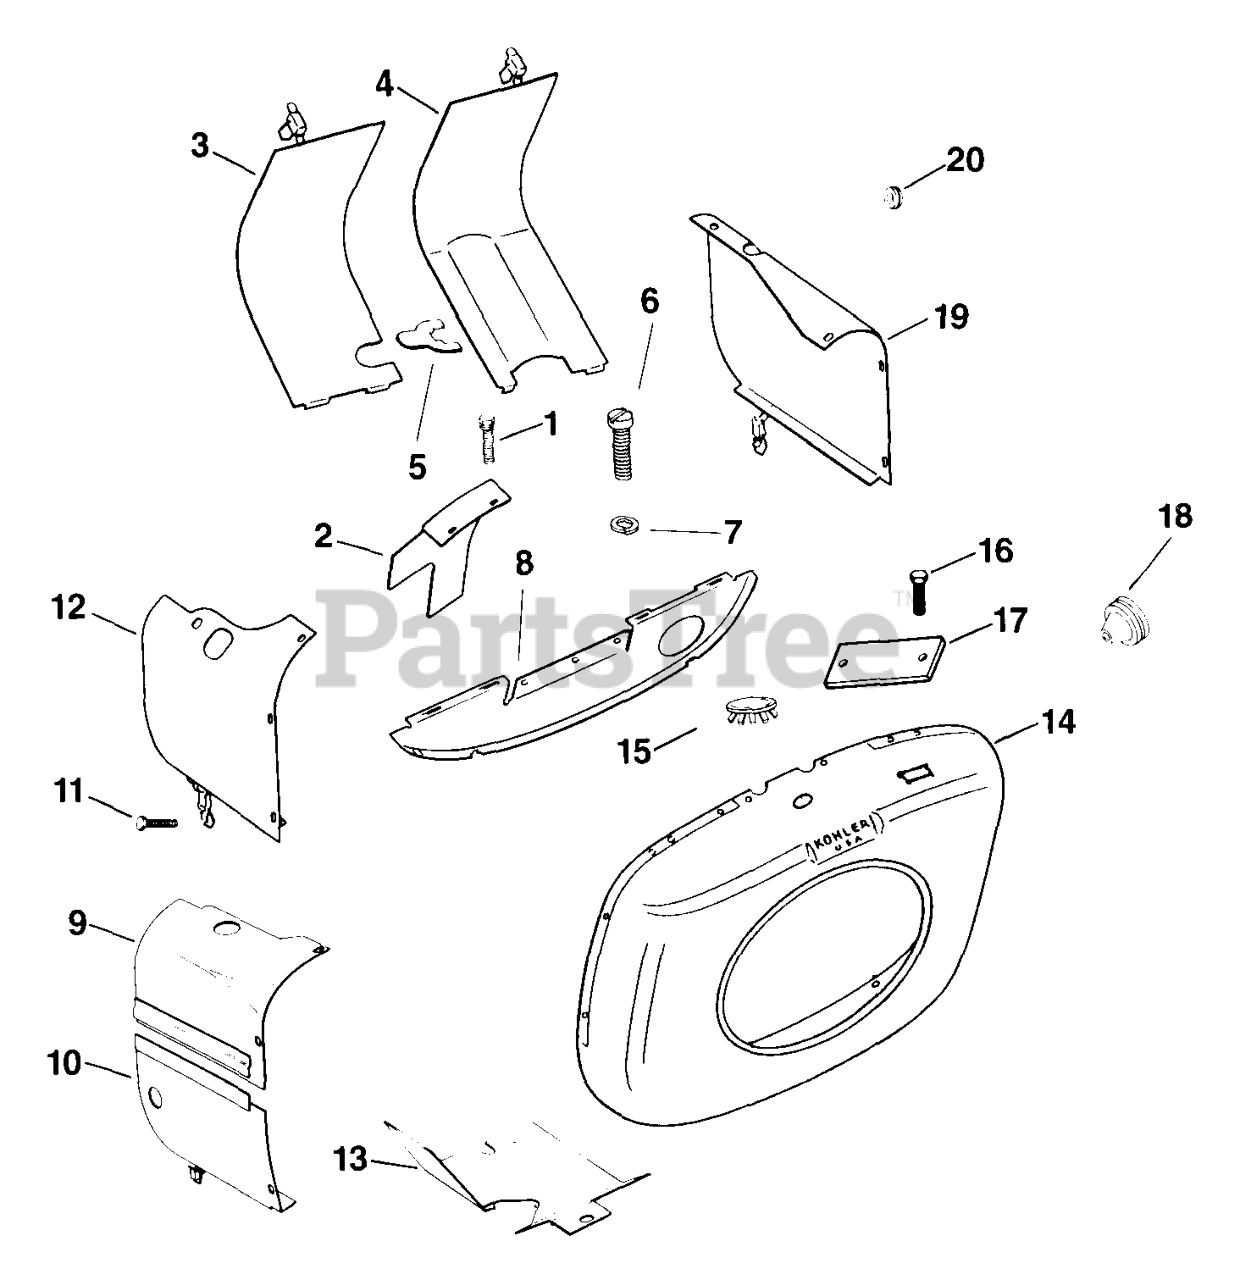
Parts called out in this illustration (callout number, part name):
6	SCREW, SLT PAN HD 1/4-20X1/2" USE 25 086 74-S
7	WASHER, SPRING LOCK 1/4"
8	BAFFLE - DISCONTINUED
11	SCREW - USE X-133-2
14	KIT, HOUSING
15	PLUG 7/8 USE 25 139 25-S
18	BUSHING - DISCONTINUED
